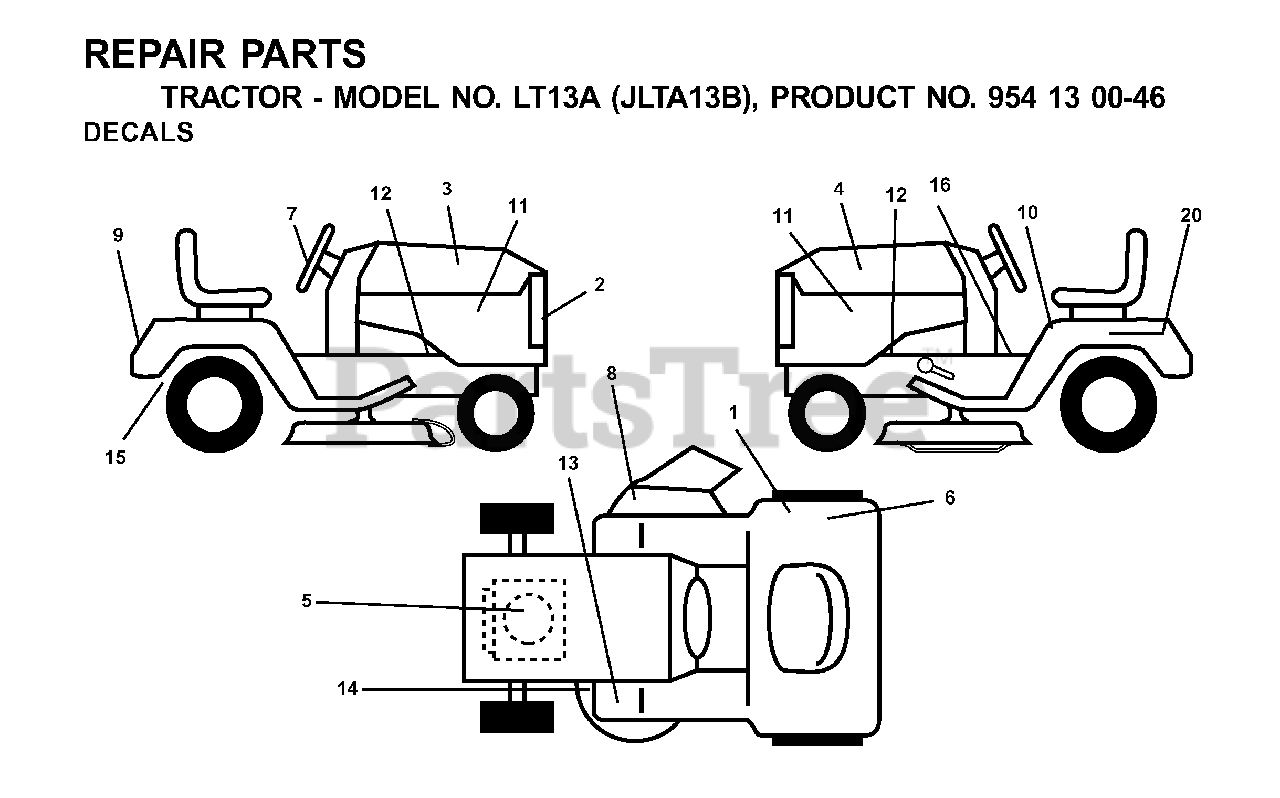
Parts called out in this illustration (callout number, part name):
1	DECAL CERTIFICATION
5	DECAL HP ENGINE
6	DECAL EUROPE STANDARD CE
8	DECAL MOWER CUT/FINGER
10	DECAL READ OWNER'S MAN SYMS
14	DECAL V-BELT SCHEMATIC
16	DECAL PARK BRAKE
20	DECAL BTRY SYMBOLS
